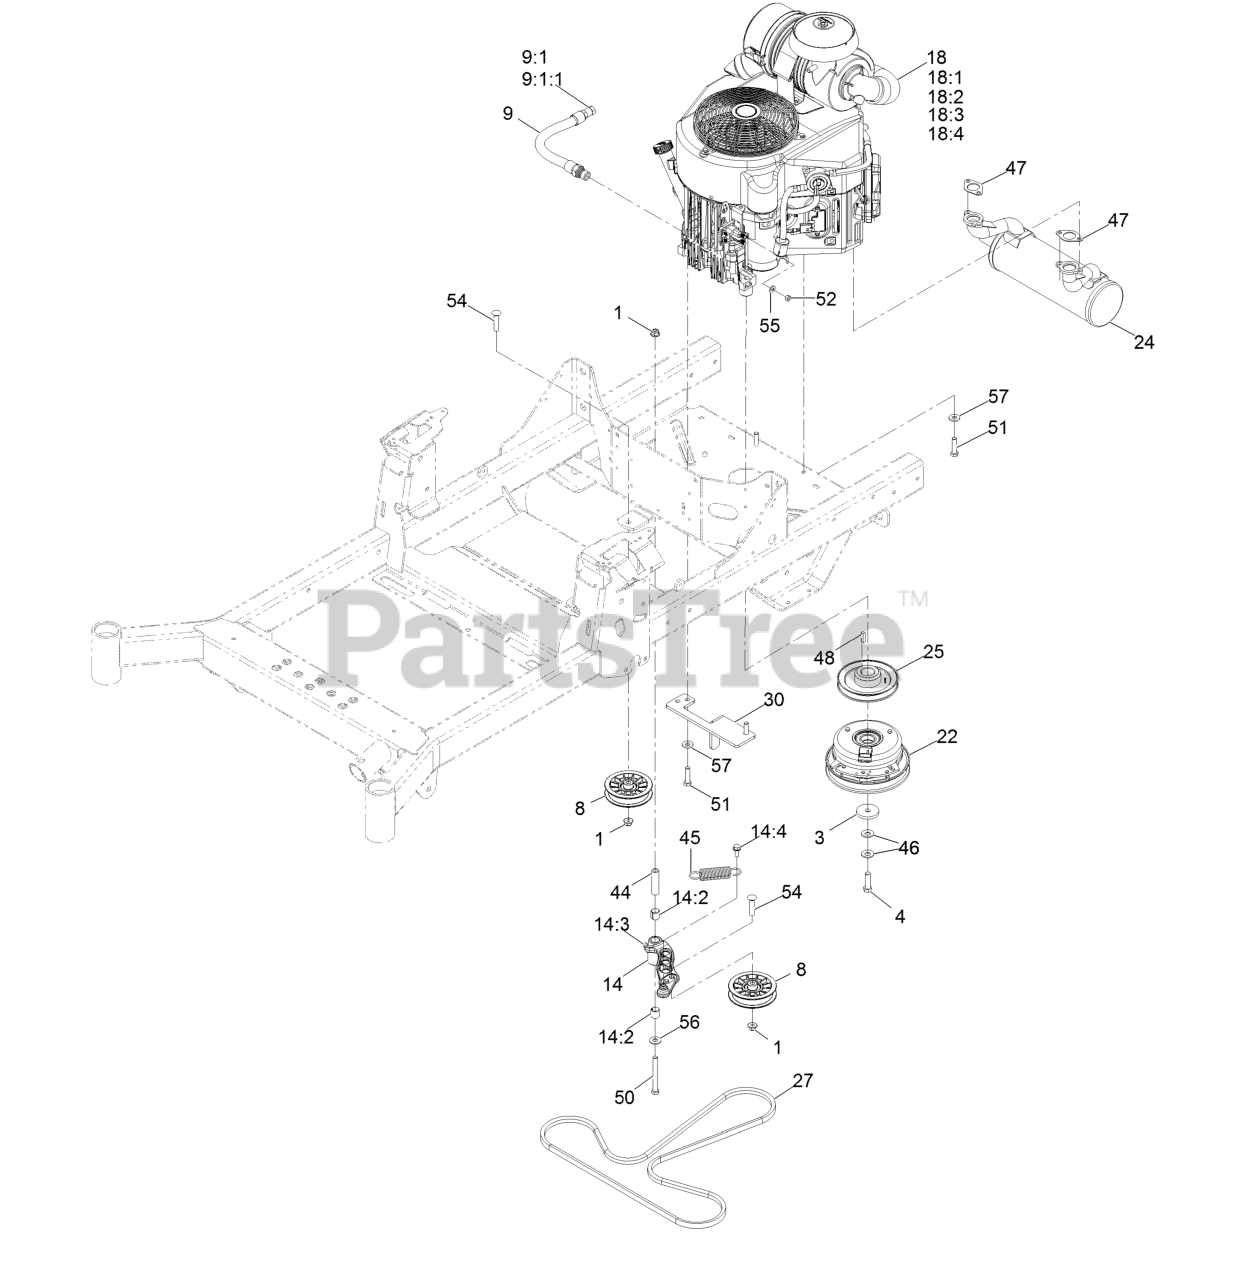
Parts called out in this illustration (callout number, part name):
1	Nut-Nyloc 3/8-16 Flg
3	Washer-Clutch
4	Screw-HH 7/16-20 X 1 1/2 W/Loctite
8	Pulley-Flat
9	Asm-Hose Oil Drain W/Plug
9:1	Plug-W/O-Ring
9:1:1	O-Ring
14	Idler Arm ASM
14:2	Sleeve-Bearing
14:3	Zerk-90deg 1/4-28
14:4	Screw-HWH 5/16-18 X 3/4 Tf
18:1	Kawasaki 49065-7007 Engine Oil Filter
18:2	Kawasaki 49019-7005 Fuel Filter
18:3	Kawasaki 11013-7045 Safety Filter
18:4	Kawasaki 11013-7044 Engine Air Filter
24	Muffler
25	Sheave (W/Hub)
27	Belt-V
30	Anchor-Clutch
44	Bushing-Pivot, Idler
45	Spring-Extension
46	Washer-Spring Disc 7/16
47	Gasket-Exhaust
48	Key-Machine 1/4 X 1/4 X 1
50	Screw-HH 3/8-16 X 3 1/2
51	Screw-HH 3/8-16 X 1 1/2
52	Nut-Hex 1/4-20
54	Bolt-Carriage 3/8-16 X 1 3/4
55	Washer-1/4 SAE
56	Washer-3/8 Std
57	Washer-Spring Disc 3/8
